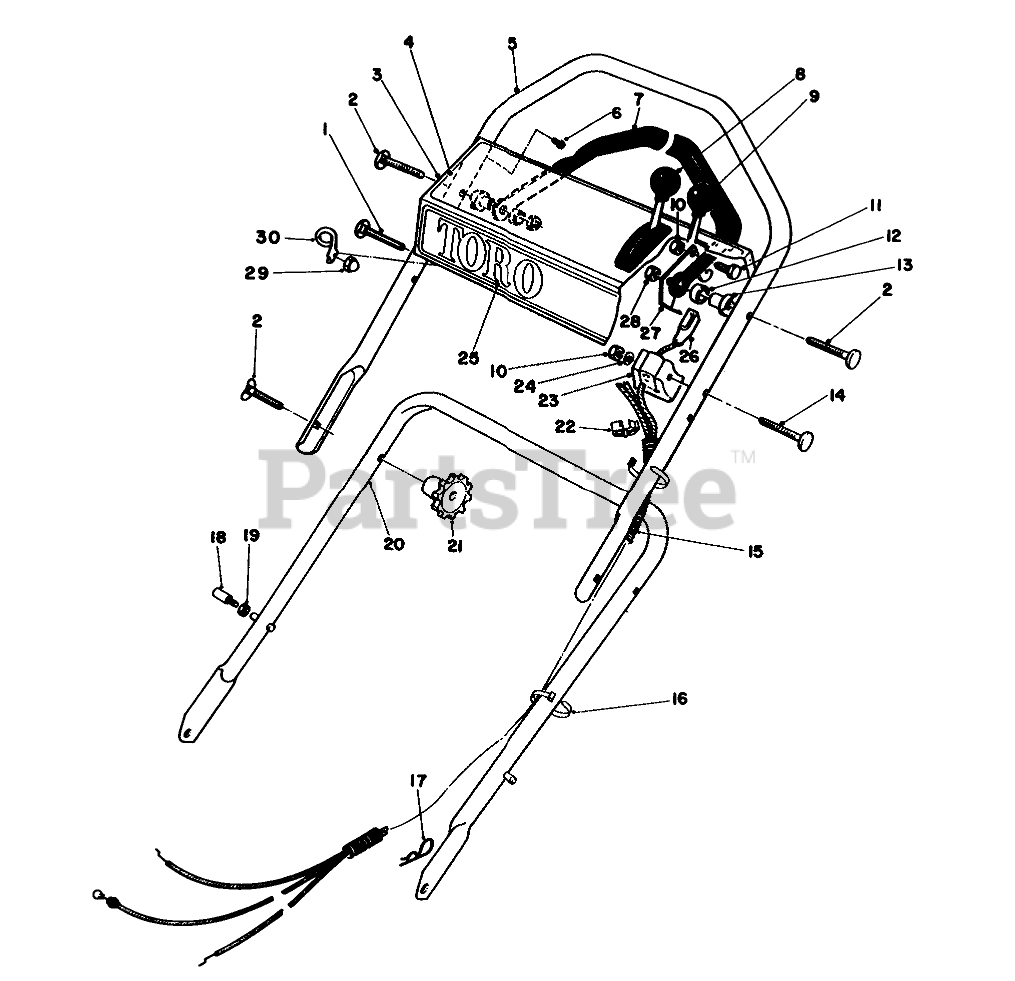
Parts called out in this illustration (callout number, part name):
1	HANDLE SCREW
2	5/16-18 X 2 HNDLE SCREW
3	Panel-Control (Incl. Ref. #4)
4	Decal-Instructions
5	Handle-Upper
6	SCREW-HWHTF
7	Bar-Control
8	SERVICE TRACT. CONTROL
9	Control-Throttle/Choke Bend Type 1 Sheath Lg. 41" Wire Lg. 21/4"
10	NUT-LOCK, NI
11	SCREW-HH
12	SPACER-NYLON
13	SPACER-SUPPORT
14	SCREW-HANDLE
15	CONT. CABLE COVER
16	TIE-CABLE
17	PIN-COTTER, HAIR
18	HANDLE PIN
19	NUT-LOCK, NI
20	LOWER HANDLE ASM
22	FITTING-RING
23	SUPPORT-CABLE
24	WASHER-FLAT
25	Decal-Toro
26	Cable-Brake
27	Lever-Control
28	NUT-LOCK, NI
29	NUT-CAP
30	Guide
